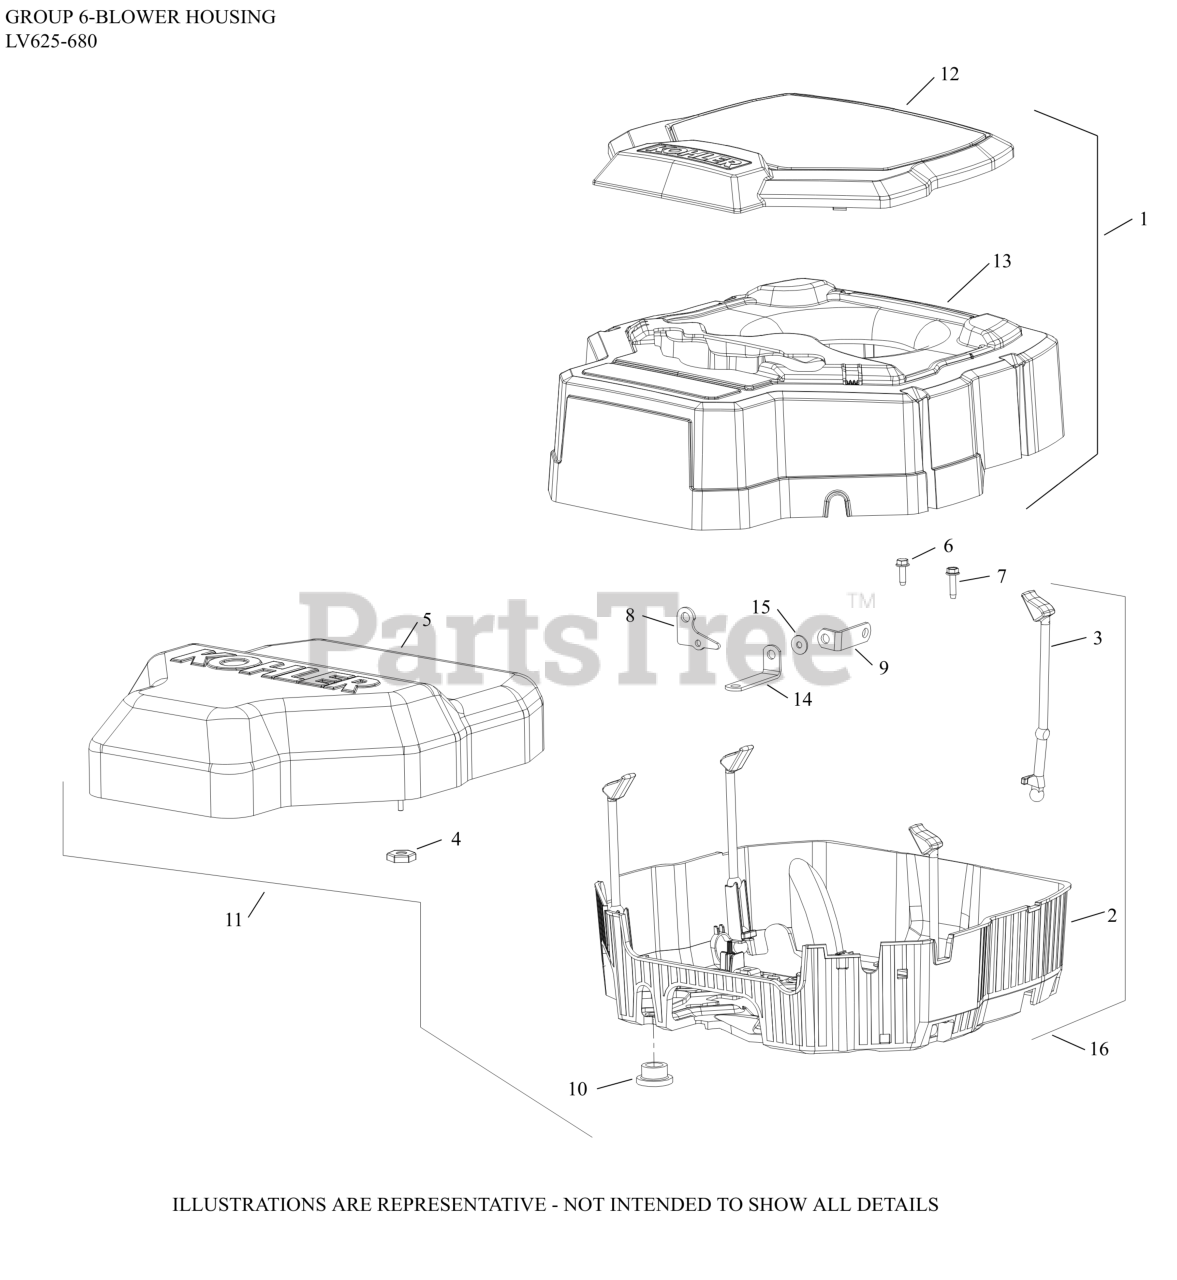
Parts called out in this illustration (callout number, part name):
2	HOUSING, LOWER ASSEMBLY - DISC.
3	STRAP, RETAINING
4	NUT, GRASS SCREEN PUSH
5	SCREEN, HEAVY DUTY GRASS
6	SCREW,FLG THD FRM M6X1.0X20-(#25086396S)
7	SCREW,FLG THD FRM M6X1.0X25-(#25086395S)
8	STRAP, LIFTING (KM)
9	STRAP, HANGING - DISCONTINUED
12	BEZEL (GREY w/OUT SCREEN)-DISC.
13	HOUSING, UPPER - STD. GRAY-DISC.
